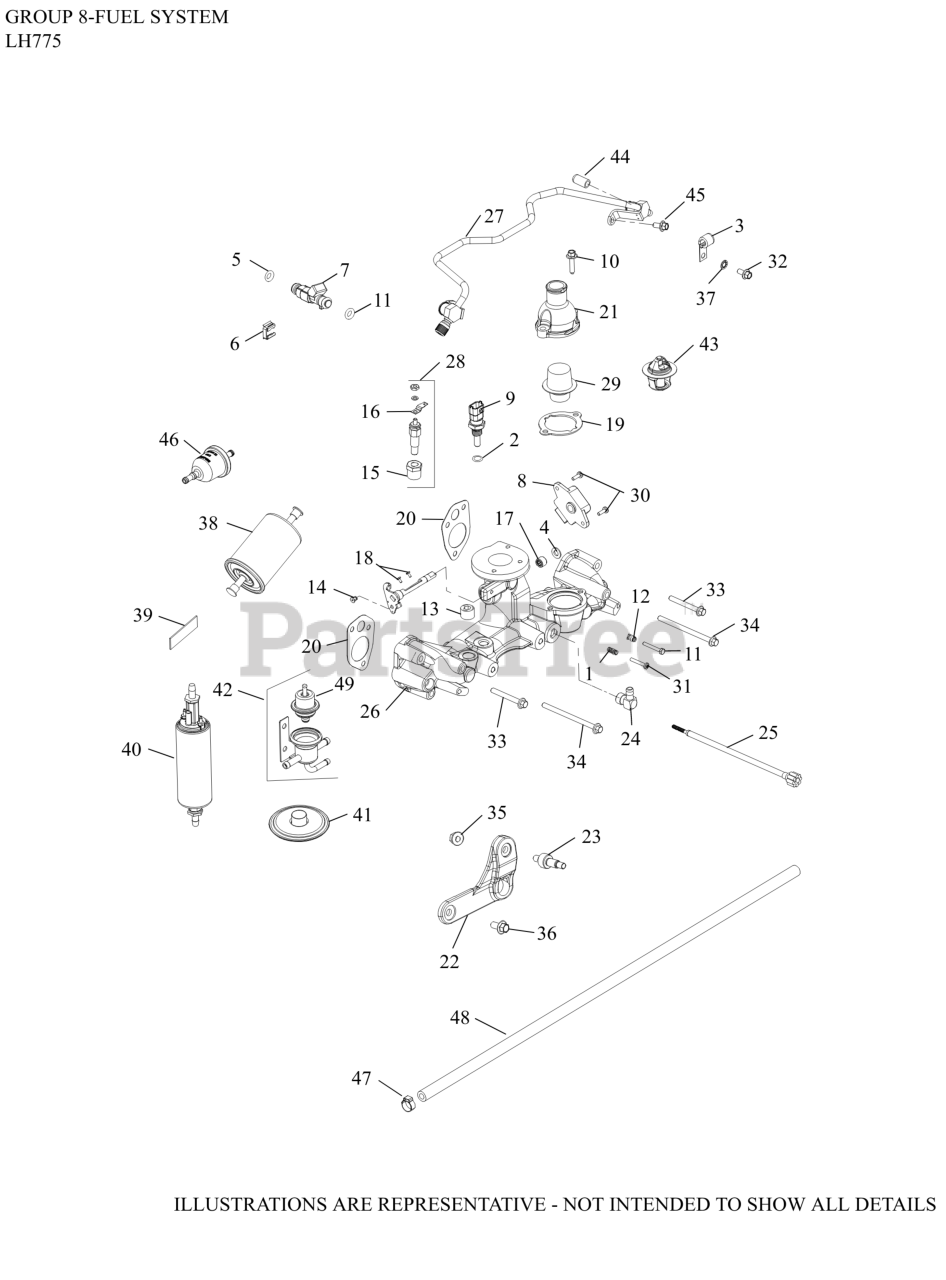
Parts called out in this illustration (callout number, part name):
2	O-RING (.5" DIA)
4	SEAL, THROTTLE SHAFT
6	CLIP, FUEL INJECTOR
7	INJECTOR, FUEL
8	KIT, THROTTLE POSITION SENSOR
9	SENSOR, TEMPERATURE (EFI)
10	SCREW, FLG M6X1.0X25
11	SCREW, HEX HD CAP (W/LOCTITE)
12	SPRING, IDLE SET SCREW
13	PLUG, PIPE CTSK 3/8"
14	BUSHING, LINKAGE RETAINING
17	BEARING, NEEDLE
19	GASKET, THERMOSTAT
20	GASKET, INTAKE MANIFOLD
21	HOUSING, THERMOSTAT
24	CONNECTOR, HOSE
26	KIT, EFI INTAKE MANIFOLD
27	RAIL, FUEL
29	KIT, THERMOSTAT (190 F degree)
30	SCREW, PHL PAN M4X0.7X12
32	SCREW, FLG M6X1.0X12
33	SCREW, FLG M6X1.0X50
34	SCREW, FLG M6X1.0X90
38	FILTER, FUEL
40	PUMP,FUEL ASSEMBLY(ELECTRIC)
42	REGULATOR ASSY, FUEL PRESSURE
44	CAP, MASKING
45	SCREW, FLG M6X1.0X12
47	CLAMP, FUEL HOSE
49	REGULATOR, FUEL PRESSURE
NI	FILTER, FUEL (EFI)-USE 24 050 22-S
